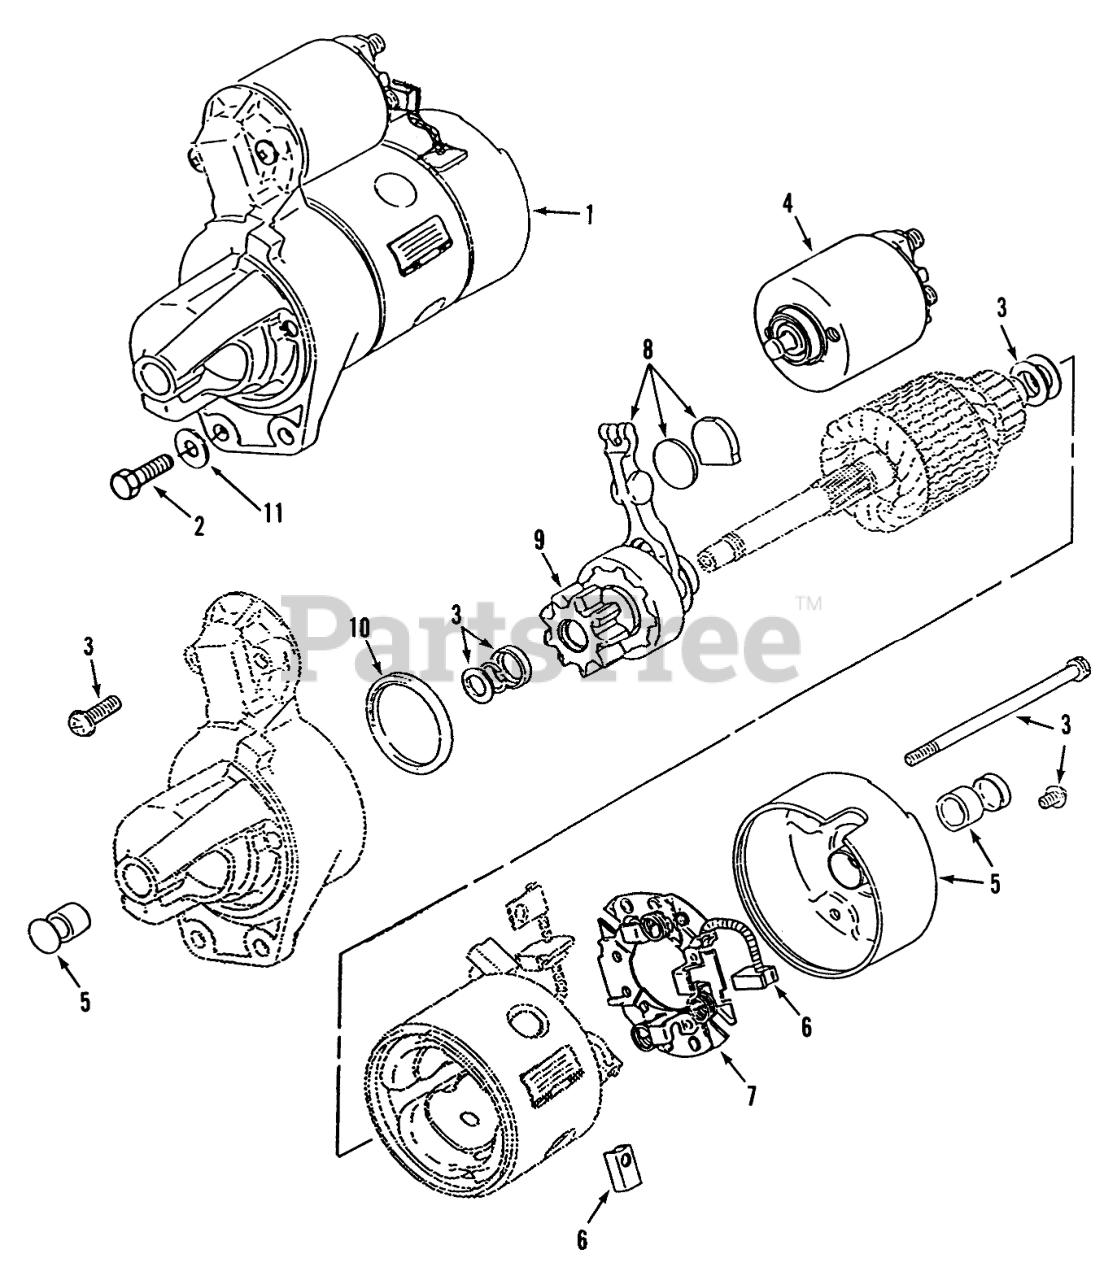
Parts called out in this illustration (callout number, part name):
1	Starter, Complete-See Components Below
2	Bolt
3	Starter Hdwr. Kit (Includes Solenoid Screws (2), Brush Holder Screws (2), Thru Bolts (2), Armature Shims (2), Pinion Stop Collar, and Pinion Retaining Ring)
4	Starter Solenoid Kit (Includes Solenoid, Spring and Plunger
5	Bushing Kit (Includes Frt. Bushing and Rear Cap w/Bushing)
6	Starter Brush Kit (Includes Positive Brush (2) and Negative Brush w/Pigtail
7	Starter Brush Holder (Includes Brush Holder w/Negative Brush)
8	Starter Shift Lever Kit (Includes Shift Lever, Wear Plate and Rubber Plug)
9	Starter Clutch (Includes Pinion Gear w/Clutch)
10	Dust Seal
11	Washer
